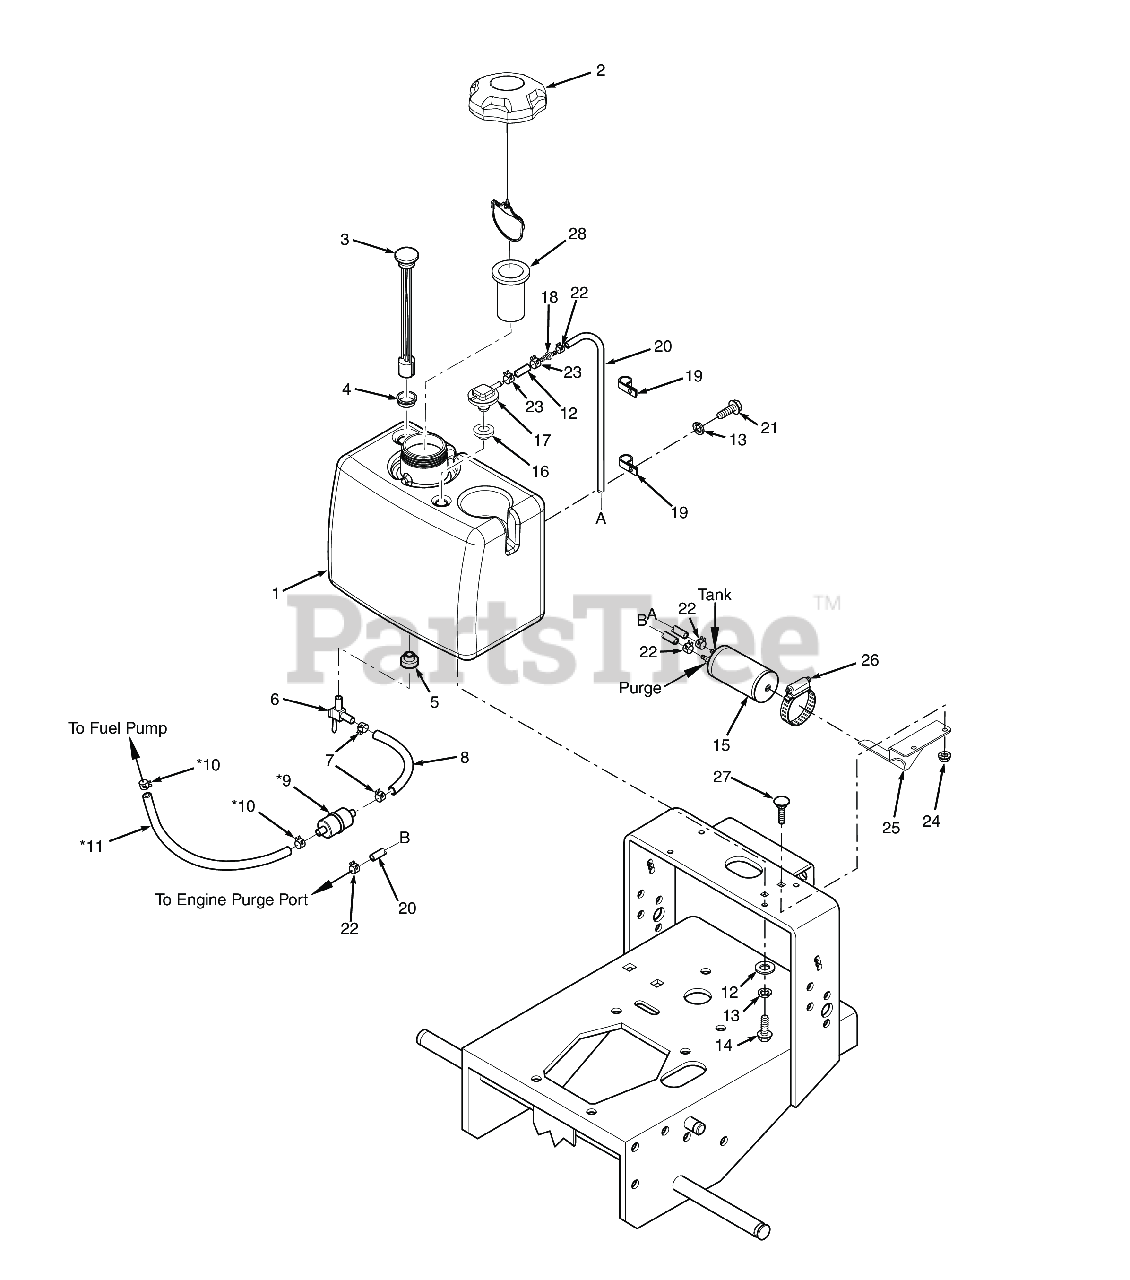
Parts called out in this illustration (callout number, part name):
1	Fuel Tank Assembly (incl. #2, 3, 5, 6, 17, 18)
2	Fuel Cap w/ Tether (E.P.A.)
3	Fuel Gauge Assembly
4	Grommet, Fuel Gauge
5	Bushing, 0.56" Dia. Viton
6	Valve, Fuel Shut Off w/Screen
7	Clamp, Fuel Hose 1/4" Hose I.D.
8	Fuel Hose, 1/4" I.D. Non-Perm (791DFI Fuel Return) - Order by Inch
9	Fuel Filter
10	Clamp, Fuel Hose
11	Fuel Hose
12	Hose, 1/4" Vapor Recovery (order by inch)
13	Lockwasher, 5/16 (.317 x .586 x .078) Helical Spring
14	Bolt, Heax Head 5/16-18 x 1" (48V / 52V)
15	Carbon Canister - SVR-36A / SVR-48V
16	Grommet, Viton,
17	Remote Vent, No Valve
18	Mender, 1/4 x 3/16 w/0.02 Hole
19	Clamp, Cable - .375 Dia.
20	Hose, Vapor Recovery 3/16" (order by inch)
21	BOLT, SERRATED FLANGE HEX HEAD 5/16-18 X 3/4"
22	Clamp, Vapor Recovery Hose 3/16"
23	CLAMP, FUEL HOSE(KAWASAKI ONLY)
24	Nut, Serrated Flange 5/16-18 (Right Front Engine Mounting, Briggs and Kohler Only)
25	Bracket, Canister Mounting
26	Clamp, 3-1/2" Max. Dia.
27	Bolt, Carriage 5/16-18x1" (large frame units only)
28	Tube, Fuel Tank Insert - 4"
